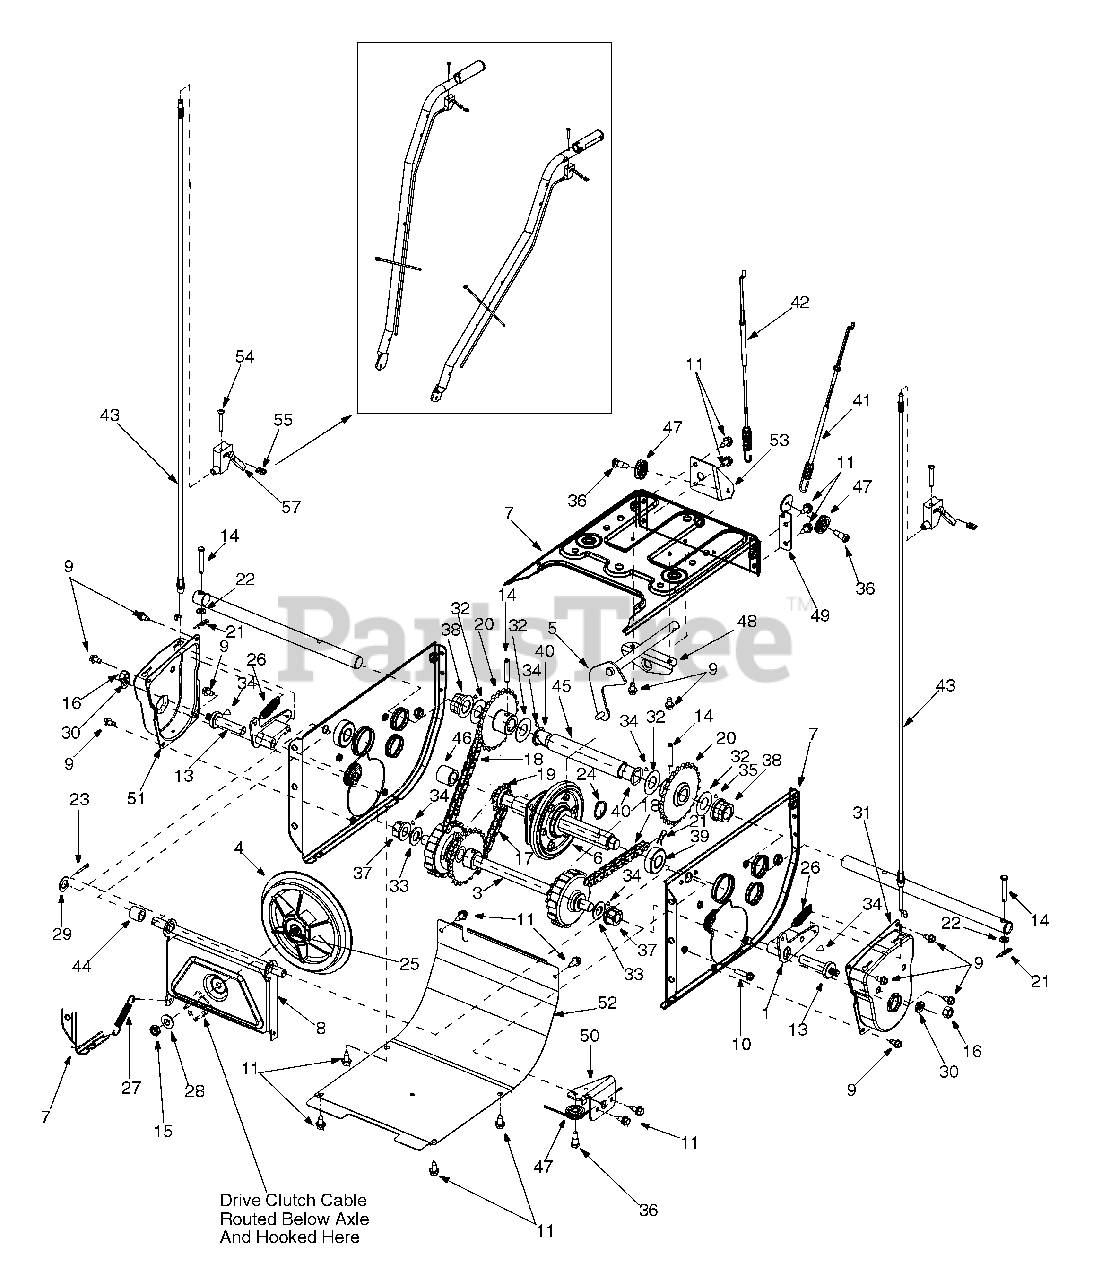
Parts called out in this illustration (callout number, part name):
1	Dogg Assembly: RH
2	Dogg Assembly: LH
3	Shift Assembly: Steerable Drive
4	Friction Wheel Disc Assy.
6	Wheel Assembly, Friction
9	Hex Washer Screw 1/4-20 x .5
10	Hex Washer Screw 1/4-20 x 1
11	Hex Screw 1/4-20 x .625"
12	Drive Shaft
13	Actuator Shaft
15	Jam Nut 3/8-24 Gr.8
16	Hex Nut: 3/8-16
19	Sprocket: 10T
21	Cotter Pin
22	Flat Washer
23	Cotter Pin
24	Snap Ring
25	Adhesive: Loctite
26	Extension Spring
27	Extension Spring
28	Bell Washer
29	Flat Washer
30	Lock Washer
33	Flat Washer
34	Lubricant: 6 in 1
35	Grease
36	Shoulder Screw
37	Hex Flange Bearing
38	Hex Flange Bearing
39	Ball Bearing
40	Flange Bushing
41	Auger Clutch Cable
42	Drive Clutch Cable
43	Steering Cable
45	Axle Support Tube
47	Roller Cable
56	Cable Tie
57	Turn Trigger
